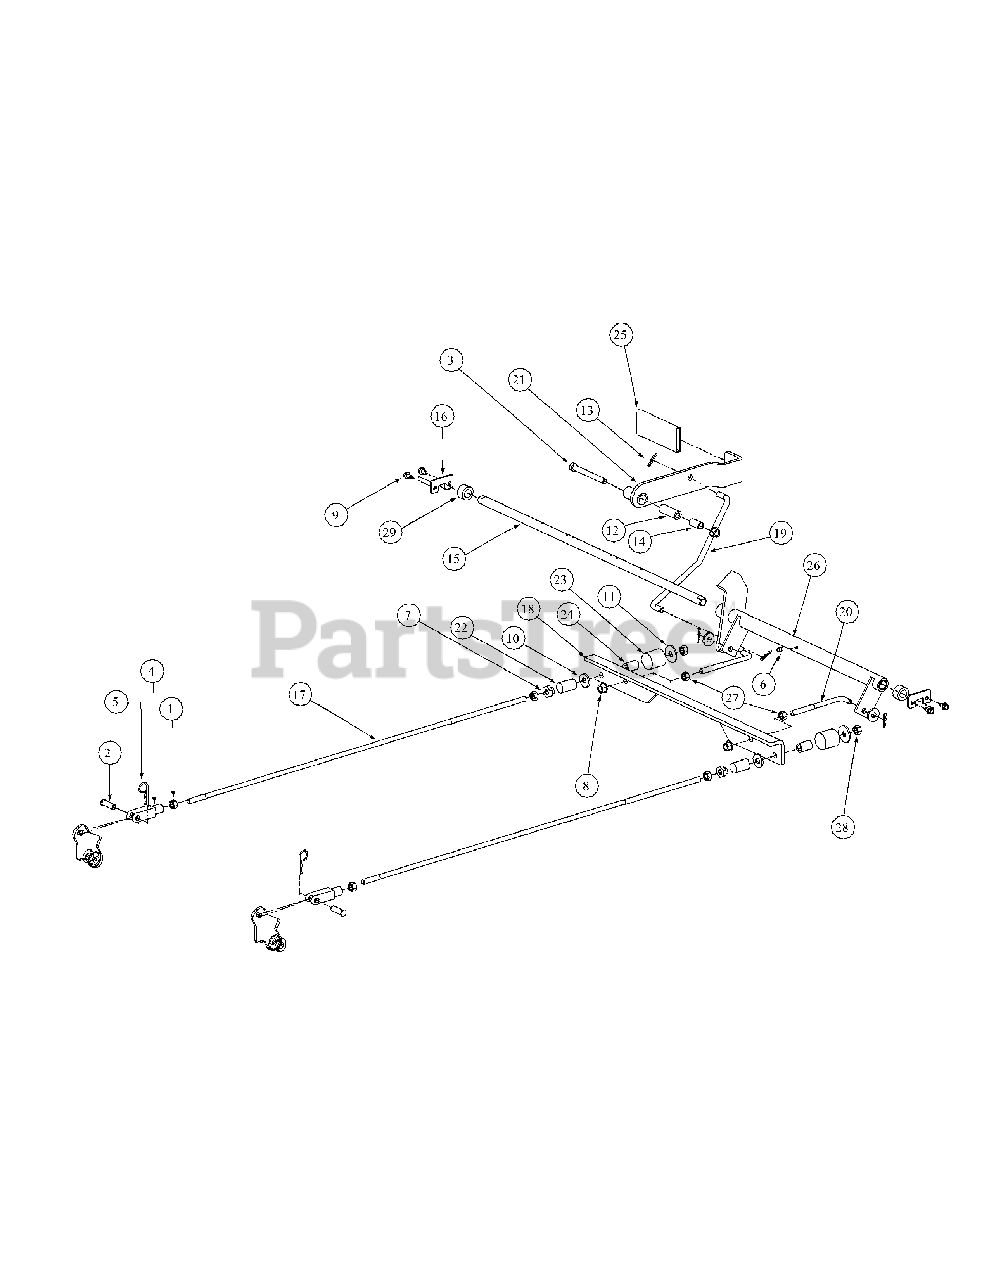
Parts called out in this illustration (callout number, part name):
1	Hex Nut, 3/8-16
2	Clevis Pin, 3/8 x 1, 1/8
3	HHCS, Standard, 3/8-16 x 3-1/2
4	Yoke, 3/8-16, Female
5	Hair Pin, 3/8"-1/2"
6	Grease Fitting, 1/4-28, 90°.
7	Shoulder Nut
8	Nut, Flange Lock, 3/8-16
9	Screw, TT, 1/4-20, .5, Hex Index Washer
10	Flat Washer, .406 ID, 1.0 OD, .105
11	Flat Washer, .411 x 1.25 x .100
12	Spacer, .39 ID x .63 OD x 1.75
13	Hair Pin, INT .072 x 1.12
14	Spacer, .375 x .50 x 1.02
15	Mounting Shaft, Bellcrank
16	Holder Shaft, Park Brake
17	Rod Connector, 3/8 OD 33
18	Brake Bracket
19	Rod Brake, Connect To Handle
20	Rod Connector, 3/8 OD x 5.75
21	Weldment, Handle Brake
22	Brake Spring, Neutral
23	Brake Spring, Force
24	Brake Hose, Center
25	Grip, Park Brake
26	Weldment Hub, Brake Bearing
26	Bearings
27	Jam Nut, 3/8-16
28	Lock Nut, Nylon Insert, 3/8-16
29	Shaft collar, .625 ID, 1" OD, .438 Lg
